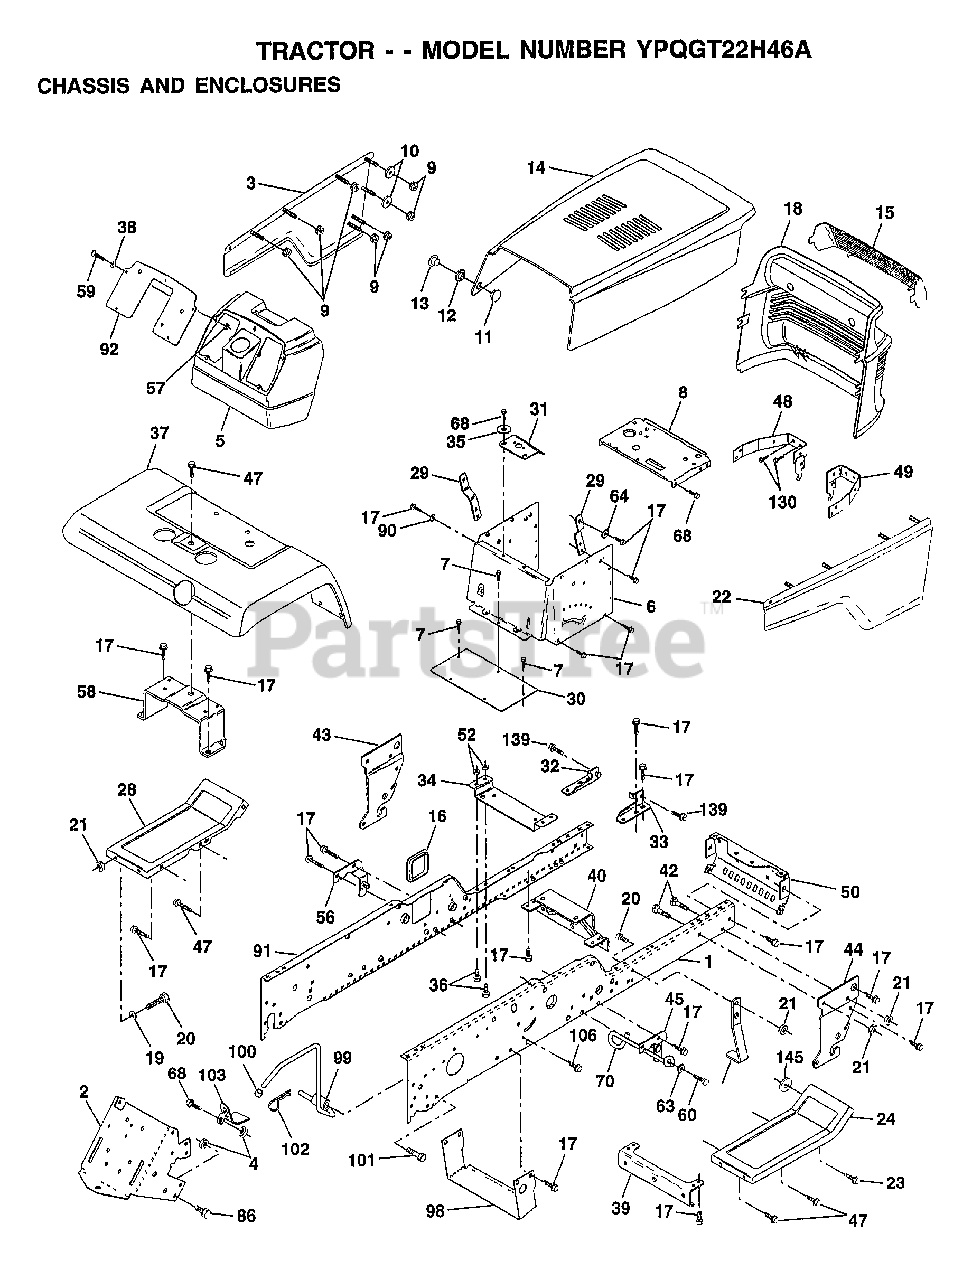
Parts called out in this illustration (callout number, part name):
1	"RAIL,FRAME RH"
2	DRAWBAR GT
3	PANEL.ASM.SIDE.LHG
4	NUT GTV
5	DASH.PLASTIC.BLK
6	DASH LOWER
7	SCREW
8	SUPPORT.DASH.BTRY
9	PAL NUT LT
10	WASHER
11	RIVET.RATCHET.MAL
12	WASHER.NYLON
13	RIVET.RATCH.FEMAL
14	HOOD.ASM.PNT
15	LENS.YT.GT.SEARS
16	COVER ACCESS
17	SCREW
19	WASHER
20	BOLT
21	NUT
22	PANEL ASM, SIDE RH
23	SCREW
24	FOOTREST.RH.LT/GT
28	FOOTREST PNT LH
29	BRACKET.SUPT.DASH
30	SADDLE.HYDRO.95
31	BRKT SUPT 1-PC VG
32	BKRT.PIVOT.CHASSIS.LH
33	BKRT.PIVOT.CHASSIS.RH
34	BRACKET.ENG.SUPT.
35	WASHER
36	BOLT
37	FENDER.PNT.YTGT.WS.
38	WASHER PM
39	BRACKET.AXLE.FRT.
40	"BRKT SUPPORT,AXLE"
43	BRACKET.SUS.FT.LH
44	BRACKET.SUS.FT.RH
45	BRACKET.SUSP.RH.
47	SCREW LT
48	BRKT ASM PIVOT LH
49	BRKT ASM PIVOT RH
50	"BRKT CHASSIS,FRNT"
56	BRACKET.SUSP.LH.
57	NUT HXKEP 1/4X20
58	BRKT.ASM.FENDER
59	SCREW
60	SCREW
63	WASHER
64	WASHER.SERRATED.
68	SCREW LT
70	GUIDE.BELT.MID.SP
84	STOP.OVER.CENTER
86	BOLT
90	LOCKWASHER
91	"RAIL FRAME,LH"
95	NUT-PUSH YT
98	BRACKET SKID CHAS
99	ROD BYPASS
101	SCREW LT
102	RETAINER M
103	LOCK BYPASS BRKT
120	WASHER HYT
130	"SCREW,HWHD.HI-LO#13-16X3/4"
139	BOLT.SHOULDER.5/16-18
145	WASHER
